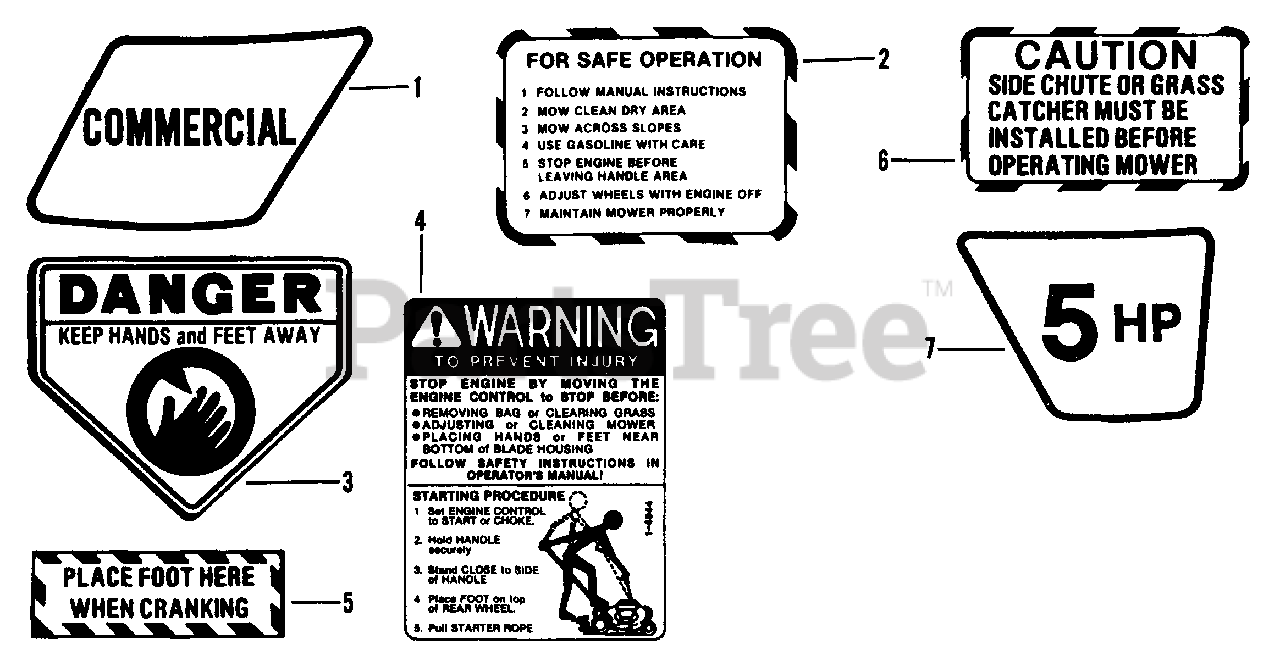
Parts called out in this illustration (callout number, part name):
1	DECAL, Commercial
2	DECAL, Safe Operation
3	DECAL, Danger
4	DECAL, Warning
5	DECAL, Cranking
6	DECAL, Caution
7	DECAL, 5 HP
